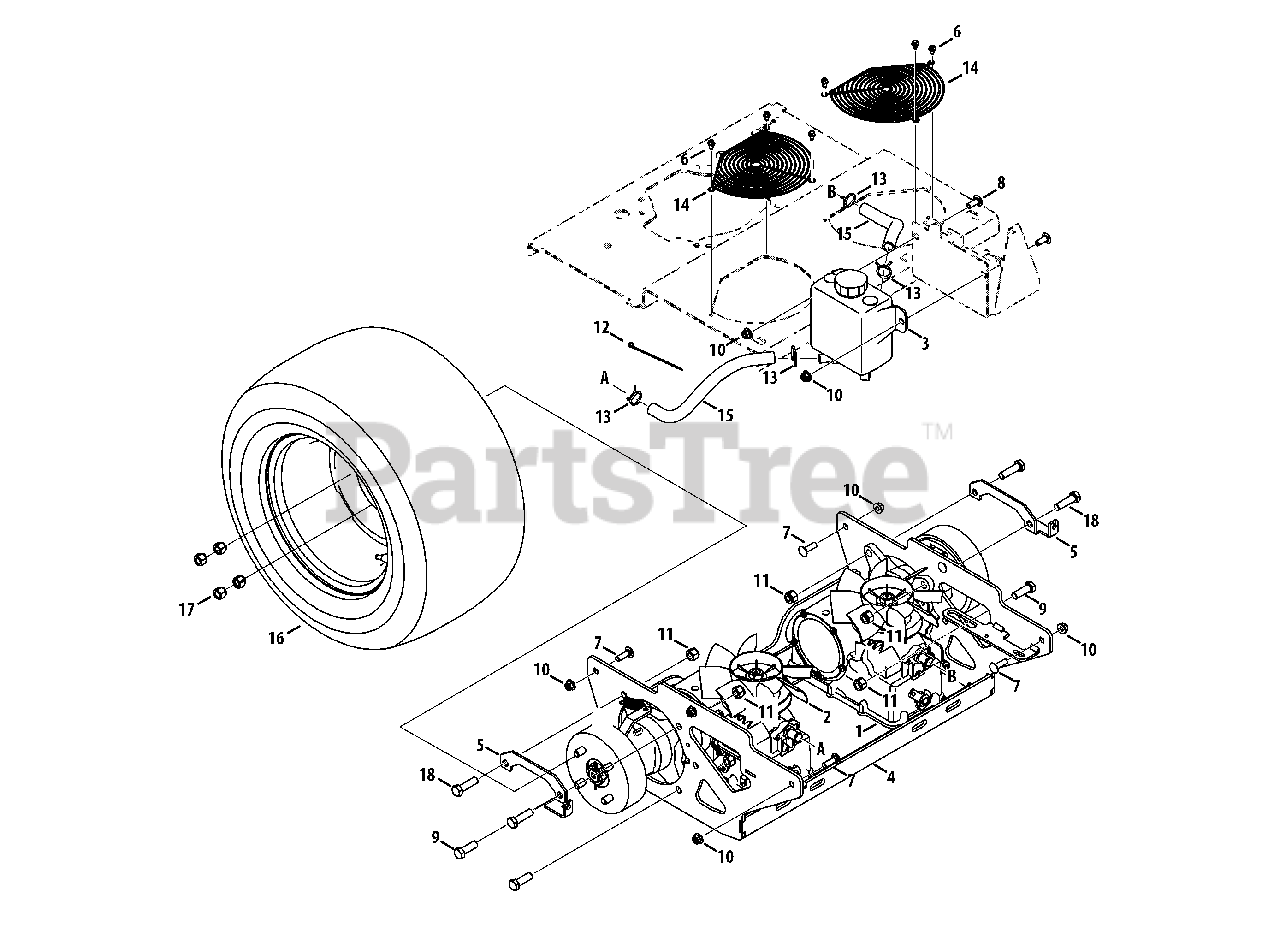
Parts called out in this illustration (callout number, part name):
1	Transmission, LH
2	Transmission, RH
3	Hydro Tank Assembly
4	Transmission Bracket Assembly
5	Transmission Brake Bracket
6	Screw, 10-24 x .500
7	Carriage Bolt, 3/8-16 x 1.25
8	Carriage Bolt, 3/8-16 x 1.00
9	Hex Cap Screw, 1/2-13 x 1.50
10	Nut, 3/8-16, Flangelock
11	Nut, 1/2-13, Flangelock
12	Cable Tie
13	Hose Clamp, .9375
15	Hose, 5/8 ID x 12.00 LG
16	Wheel Assembly, 24 x 9.5-12 (48")
17	Lug Nut, 1/2-13
18	Hex Cap Screw, 1/2-13 x 1.75
